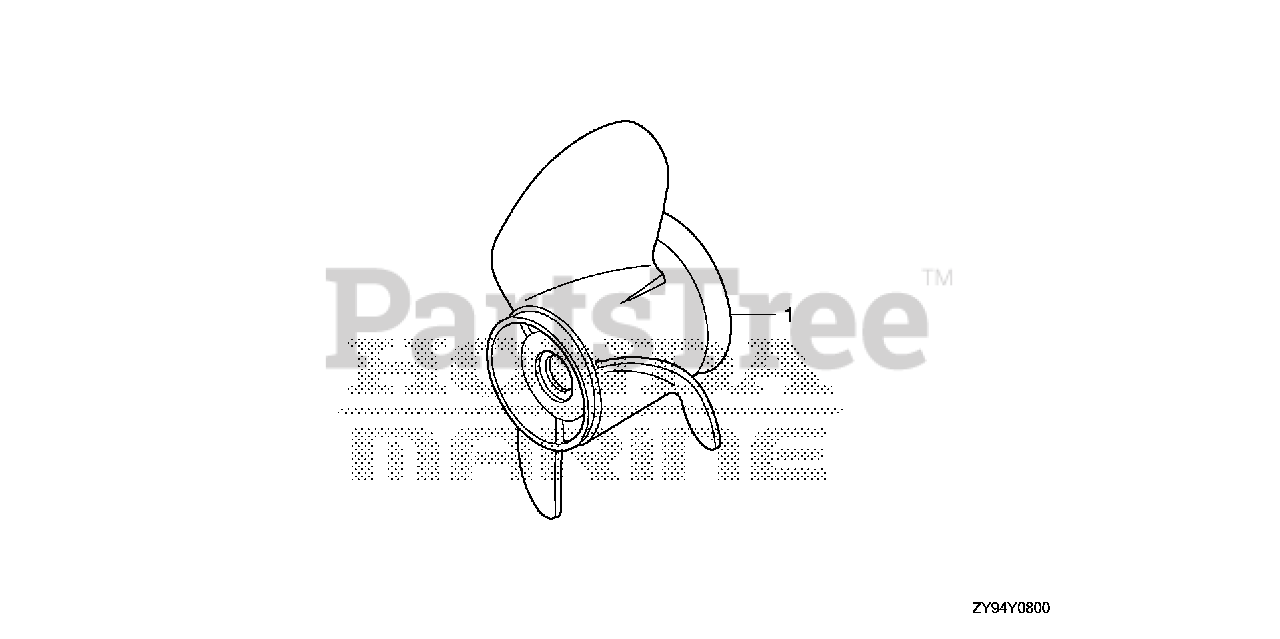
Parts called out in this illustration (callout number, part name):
1	PROPELLER, THREE-BLADE (13X19) (SUS) Use from Frame SN 1302132.
1	PROPELLER, THREE-BLADE (13X21) (SUS) Use from Frame SN 1302132.
1	PROPELLER, THREE-BLADE (14X11) *NH283* (AL) Use from Frame SN 1302160.
1	PROPELLER, THREE-BLADE (13-3/4X13) *NH283* (AL) Use from Frame SN 1302160.
1	PROPELLER, THREE-BLADE (13-1/4X17) *NH283* (AL) Use from Frame SN 1302160.
1	PROPELLER, THREE-BLADE (13X21) *NH283* (AL) Use from Frame SN 1302160.
1	PROPELLER, THREE-BLADE (13X19) *NH283* (AL) (STIN GRAY)
1	PROPELLER, THREE-BLADE (13-1/4X17) (SUS) Use from Frame SN 1302160.
1	PROPELLER, THREE-BLADE (13-1/2X15) *NH283* (AL) (STIN GRAY)
1	PROPELLER, THREE-BLADE (13-1/4X15) (SUS/HAC)
1	PROPELLER, THREE-BLADE (13-1/4X17) (SUS/HAC)
1	PROPELLER, THREE-BLADE (13-1/4X19) (SUS/HAC)
1	PROPELLER, THREE-BLADE (13-1/4X21) (SUS/HAC)
1	PROPELLER, THREE-BLADE (13-1/5X19) *NH283* (STIN GRAY)
1	PROPELLER, THREE-BLADE (13-1/5X21) *NH283* (STIN GRAY)
